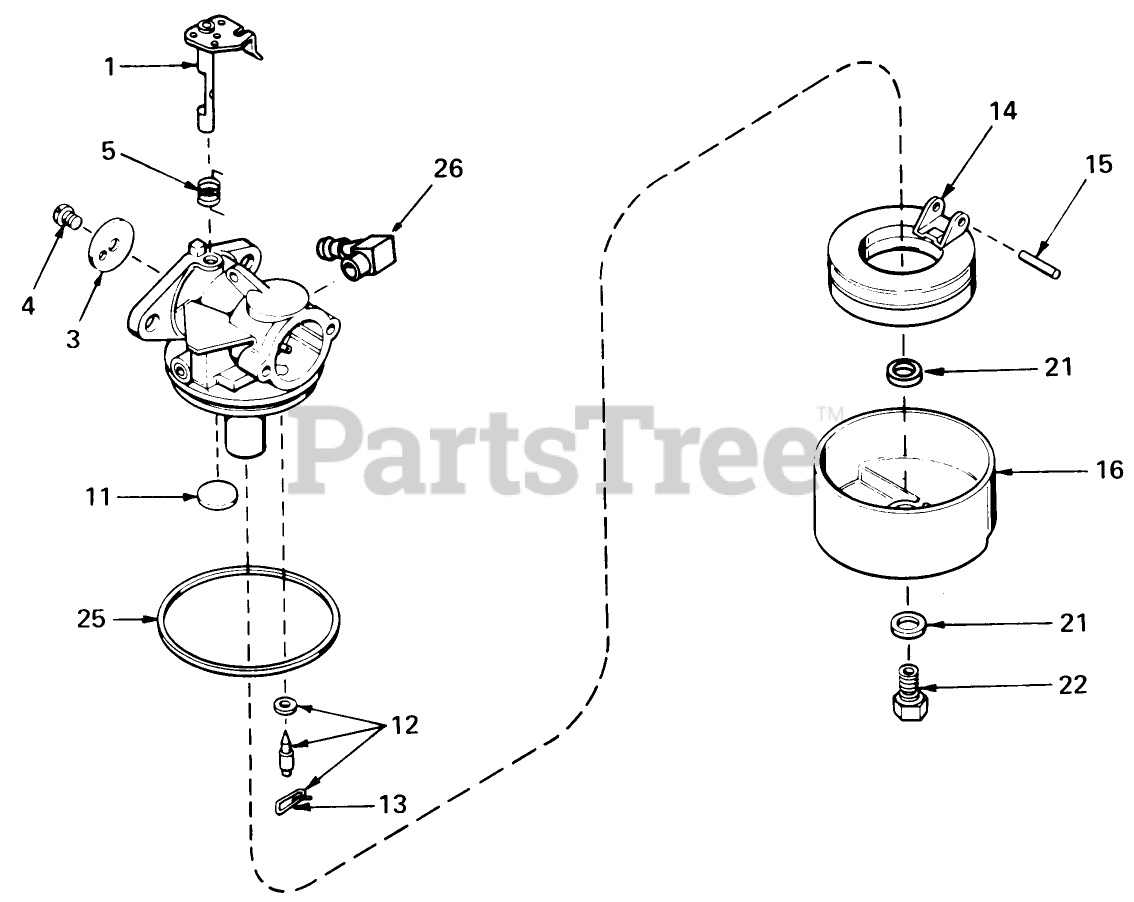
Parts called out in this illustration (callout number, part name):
1	Throttle Shaft and Lever ASM
3	Throttle-Shutter
4	Screw-Shutter
5	Spring, Return
11	Plug-Welch, Atmospheric Vent
12	Inlet Needle, Seat Clip Assy. (Incl. No. 13)
13	Clip-Spring
14	Float,Carburetor
15	Shaft-Float
16	Bowl Float
21	Gasket-Bowl
22	Nut-Float Bowl
25	O Ring-Bowl, Float
26	Fitting-Fuel
